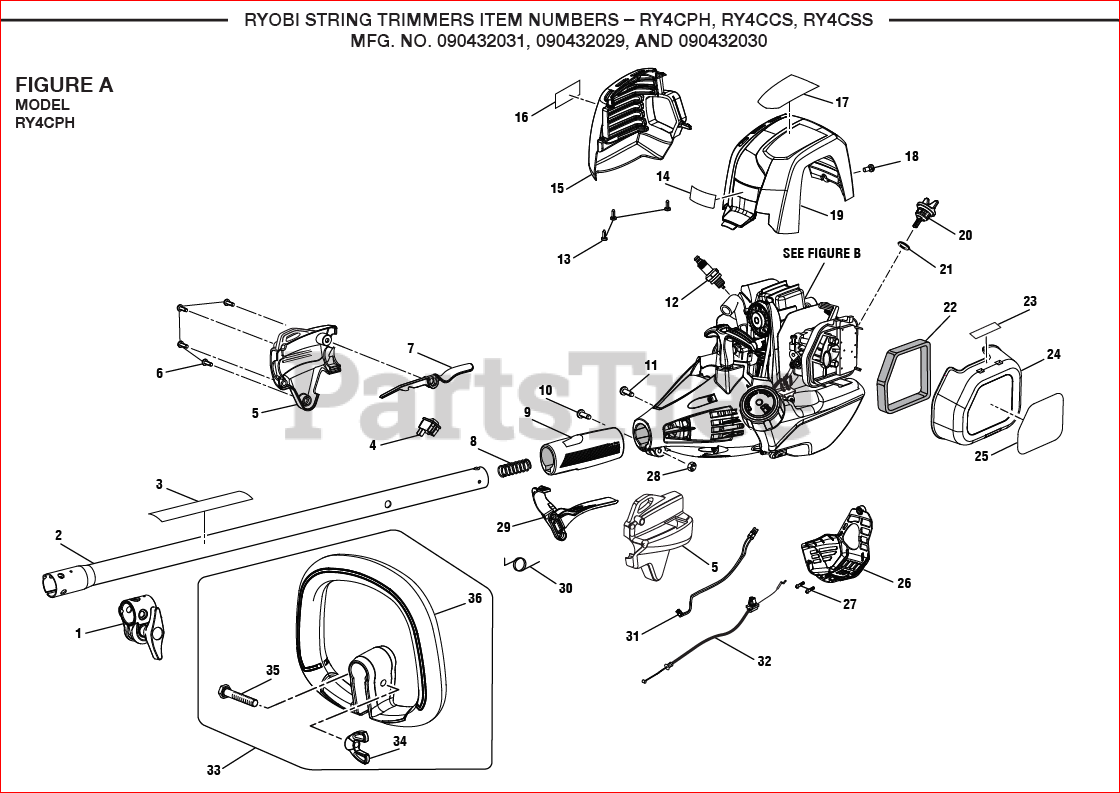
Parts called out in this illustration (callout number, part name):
1	Boom Clamp Assembly
2	Upper Boom Assembly
3	Warning Icon Label
4	Stop Switch (Momentary Contact)
5	Control Handle Assembly (Inc. Key No. 6)
6	Screw (M4 x 20 mm, T20 Torx Pan Hd. S.T.)
7	Trigger Lock
8	COMPRESSION SPRING
9	Rear Handle Grip
10	Screw (M6 x 20 mm, T27 Torx Button Hd.)
11	Screw (M4 x 8 mm, T25 Torx Pan Hd. T.F.)
12	Spark Plug (Champion RY4C)
13	Screw (M4 x 12 mm, T20 Torx Truss Hd.)
14	Logo Label
15	Muffler Housing (Inc. Key No. 16)
16	Warning Label (Combustion)
17	X430 Label (RY34006)
18	Shoulder Screw (M4 x 11 mm, T25 Torx Pan Hd.)
19	Top Cover
20	Oil Cap/Dipstick (Incl. key no. 12)
22	Air Filter
23	Choke Label
24	Air Filter Cover
25	Starting Label
26	CE Cover (Bottom Cover)
27	Screw (#6-19 x 1/2 in., Phillips Hd. T.F.)
28	Hex Nut (M6.3 x 1)
29	Throttle Trigger
30	Torsion Spring (Throttle Trigger)
31	Lead Assembly (Inc. Key No. 4)
32	Throttle Cable
33	Front Handle Assembly
34	Wing Nut (1/4-20, Plastic)
35	Screw (1/4-20 x 40 mm, Cap Hex Hd.)
36	Front Handle
